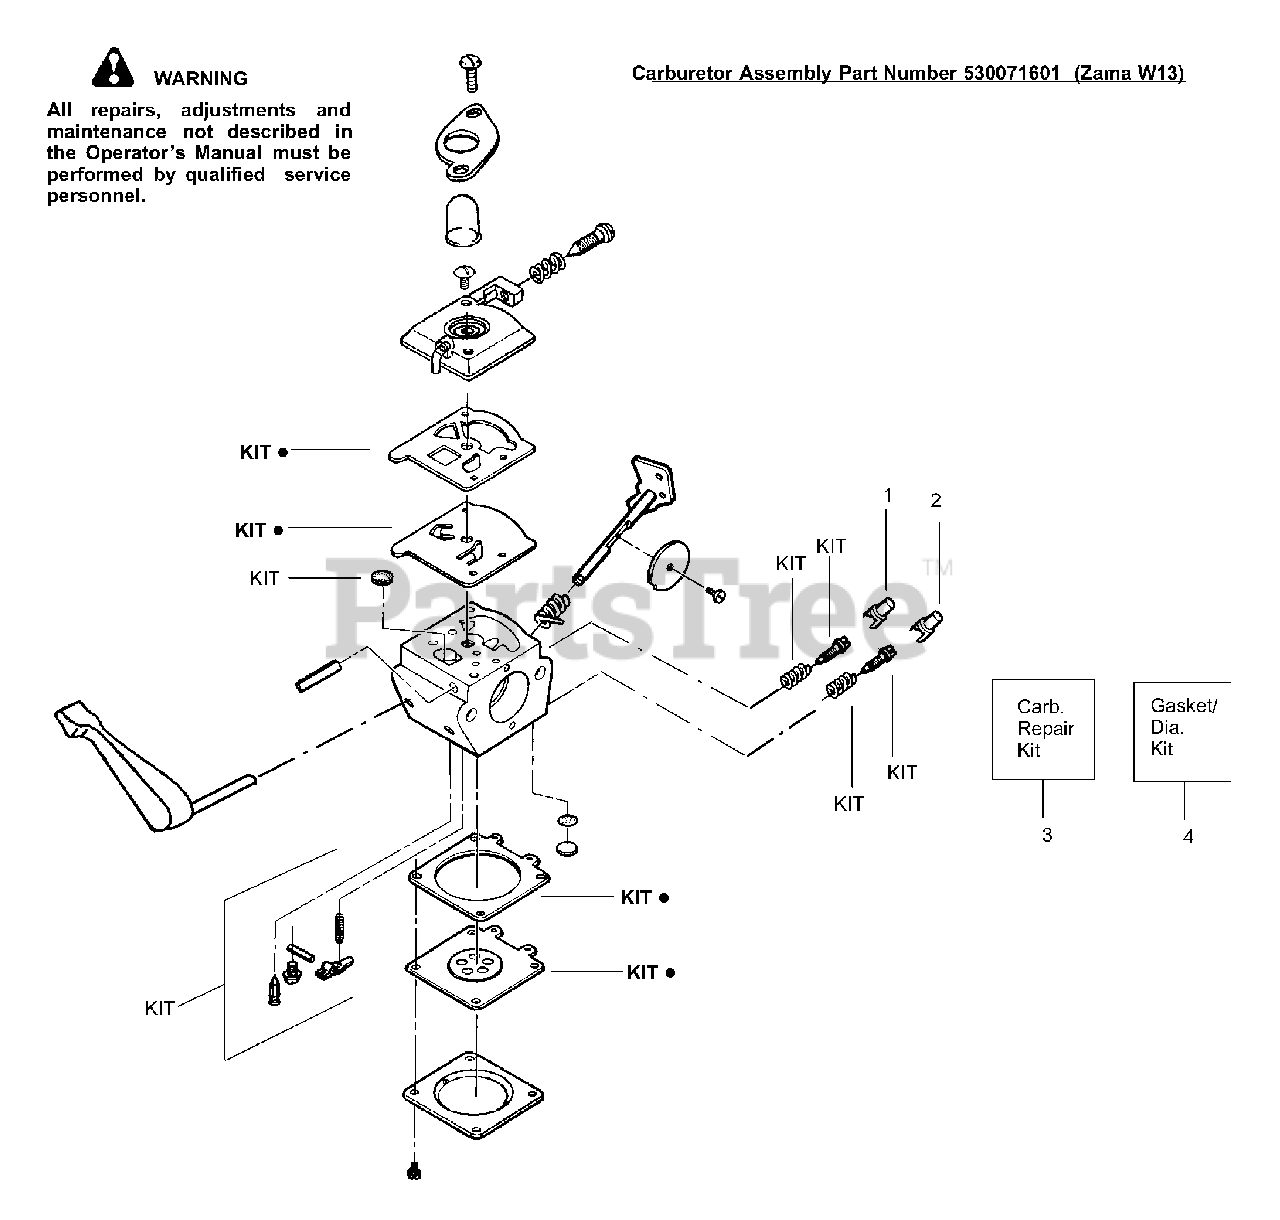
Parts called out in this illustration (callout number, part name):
1	Limiter Cap-Low
2	Limiter Cap-High
3	Carburetor Repair Kit
4	Gasket/Diaphragm Kit
530071601	Carburetor Assembly - Zama W13
